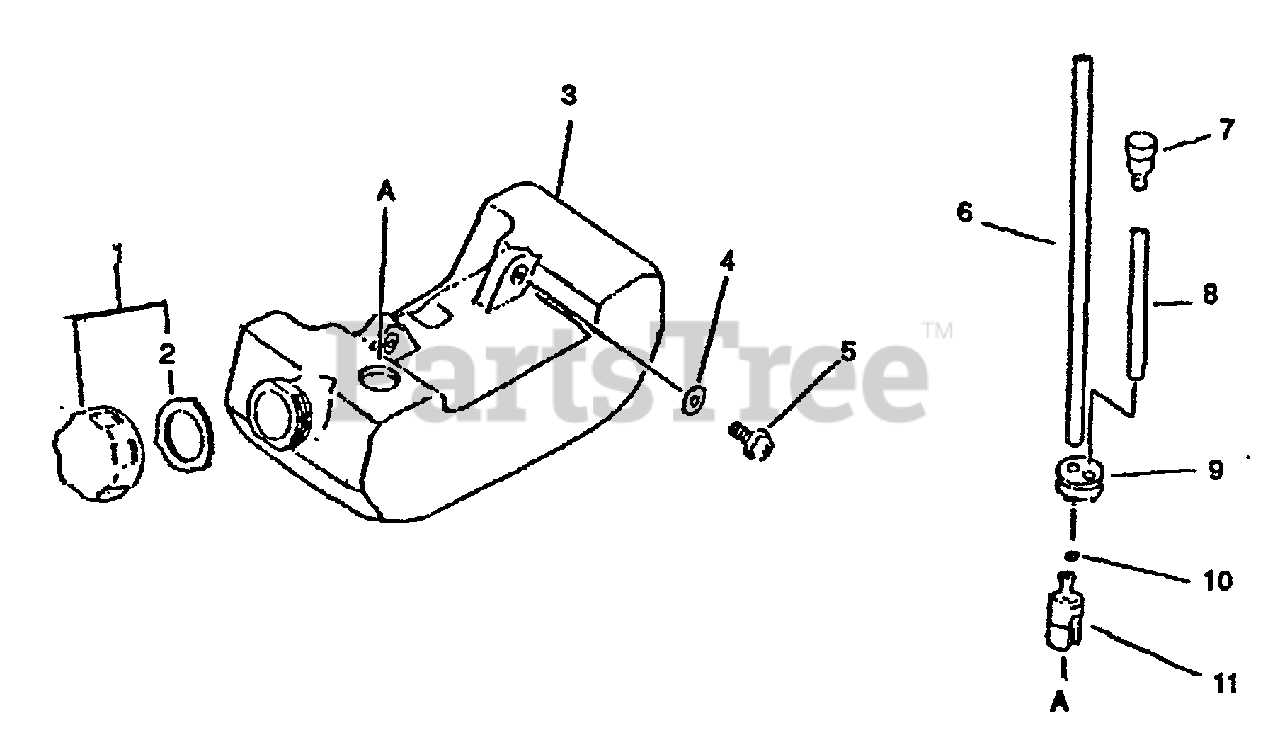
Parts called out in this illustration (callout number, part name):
1	Cap Asy, Fuel Tank
2	Gasket, Fuel Tank Cap
3	Tank, Fuel
4	Washer 5
5	Screw 5X16
6	Pipe, Fuel
7	Vent Asy
8	Pipe 3X5X70
9	Grommet
11	Strainer, Fuel
